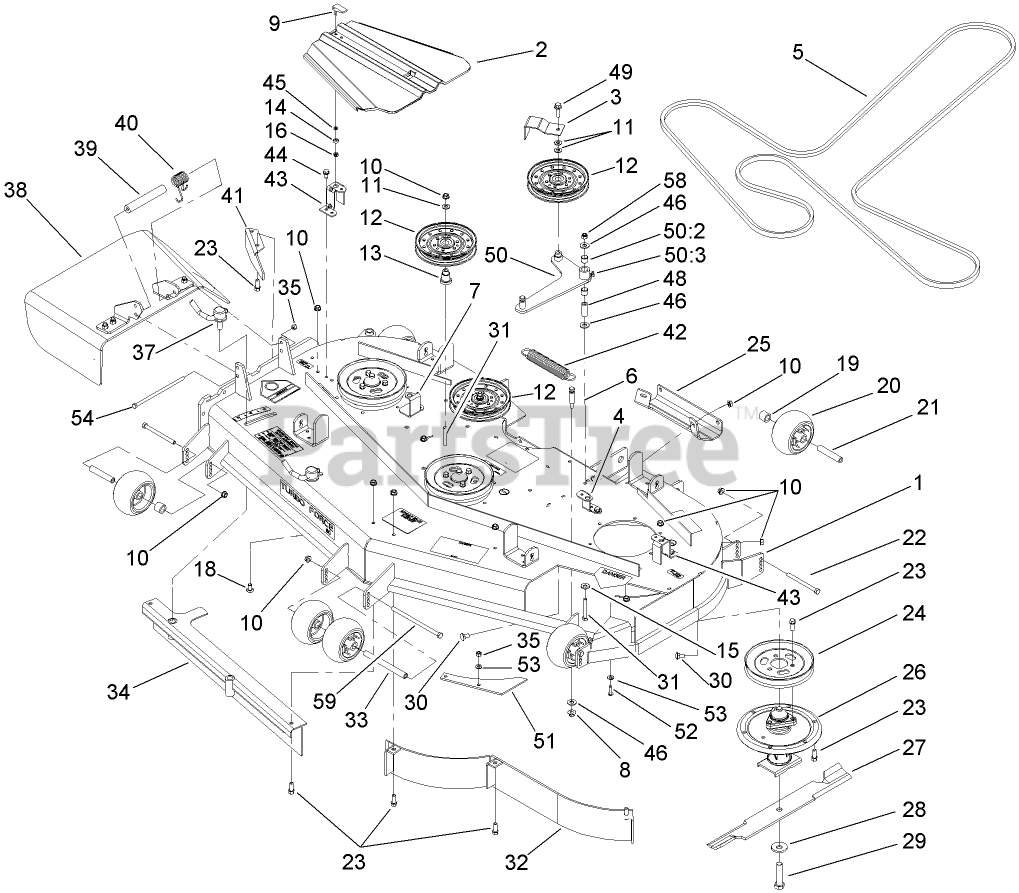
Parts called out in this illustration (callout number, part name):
1	DECK DECAL ASM
2	COVER-BELT
3	GUIDE-BELT
4	BRACKET-COVER, TALL
5	BELT-V
6	PIN-THREADED, SPRING ANCHOR
7	BRACKET-COVER
8	NUT-HF
9	HANDLE-LATCH, SWELL
10	NUT-HHF, WHIZ
11	WASHER-FLAT
12	Idler-Flat
13	MOUNT-PULLEY
14	BUSHING-LATCH, SWELL
15	WASHER-BELLEVILLE
16	NUT-LOCK, HH
18	SCREW-CARR
19	TUBE-SPACER
20	ROLLER-SCALP, ANTI
21	TUBE-SPANNER
22	SCREW-HH
23	SCREW-HWH
24	Pulley
25	Plate-Skid
26	SPINDLE ASM
27	BLADE-HI FLOW
28	Washer-Blade Bolt, Heavy
29	Screw-Cap
30	SCREW-CARR
31	SCREW-HH
33	SPACER-WHEEL
35	NUT-LOCK, NI
37	LEVER ASM
38	RUBBER DEFLECTOR ASM
39	SPACER
40	SPRING-TORSION
41	BAFFLE-DISCHARGE
42	SPRING-EXTENSION
43	BRACKET-COVER
44	SCREW-HWHTF
45	WASHER
46	WASHER-FLAT
48	BUSHING
49	SCREW-HHF
50	DECK IDLER ARM ASM
50:2	SLEEVE-BEARING
50:3	FITTING-GREASE, 90 DEG
51	PLATE-TURBO
52	SCREW-HSBH
53	WASHER-SPRING
54	SCREW-HH
58	NUT-LOCK, NI
59	SCREW-HH
